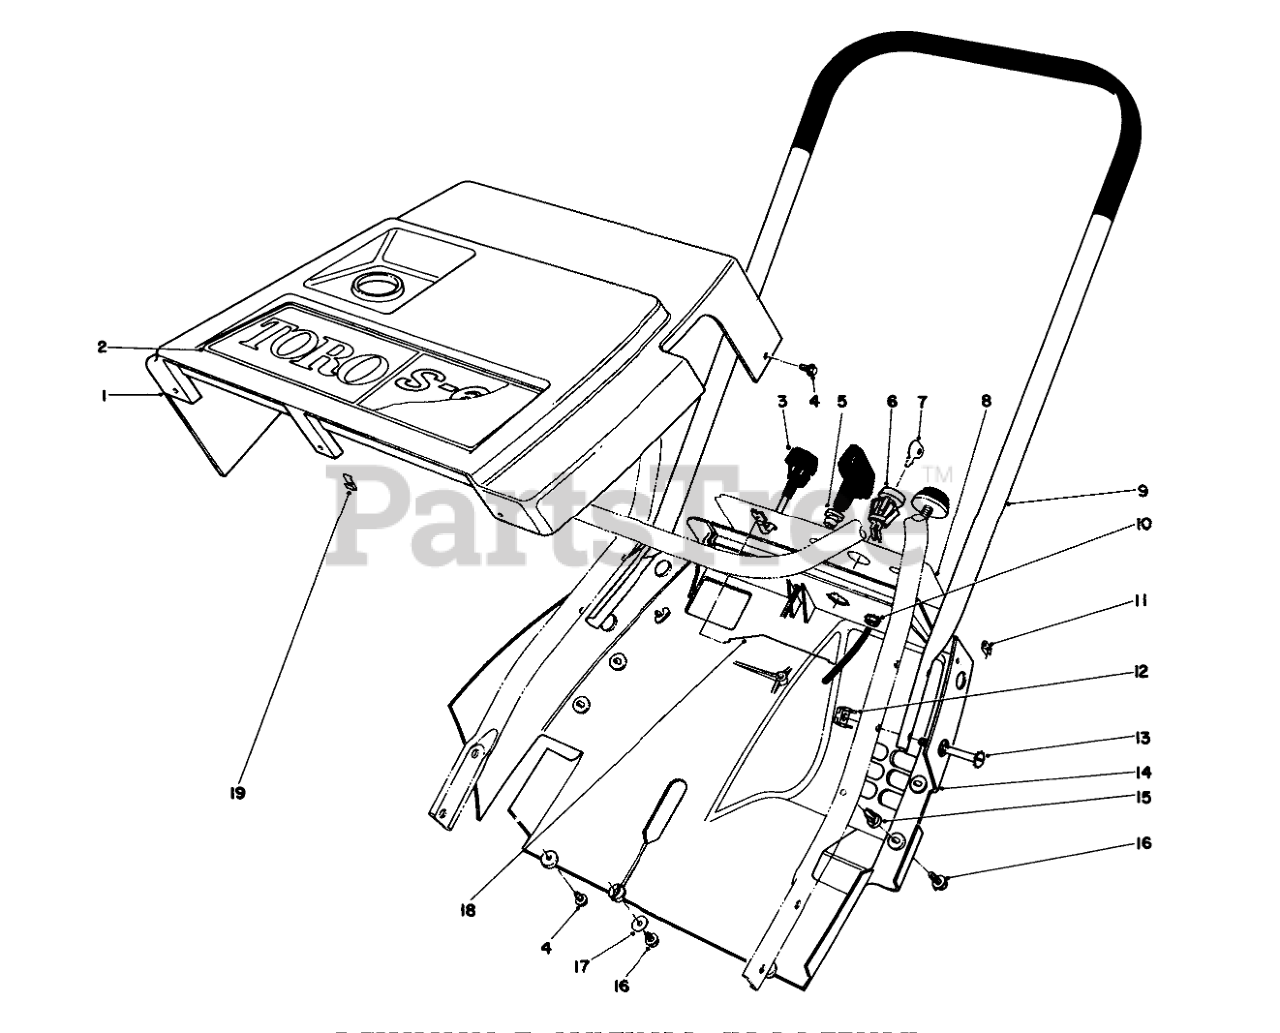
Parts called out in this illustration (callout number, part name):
1	Shroud-Upper
2	TORO DECAL
3	CHOKE CONTROL ASM
4	SCREW-HWHTF
5	GUIDE-ROPE, STARTER
6	SWITCH
7	Key
8	Decal-Control Panel
9	Handle-Upper
10	NUT-KEPS
12	TINNERMAN NUT
13	SCREW-HEX HD SLOT
14	LOWER SHROUD
15	Nut-Push In
16	SCREW-HWHTF
17	WASHER-FLAT
18	CONTROL WIRE
19	NUT "U"
